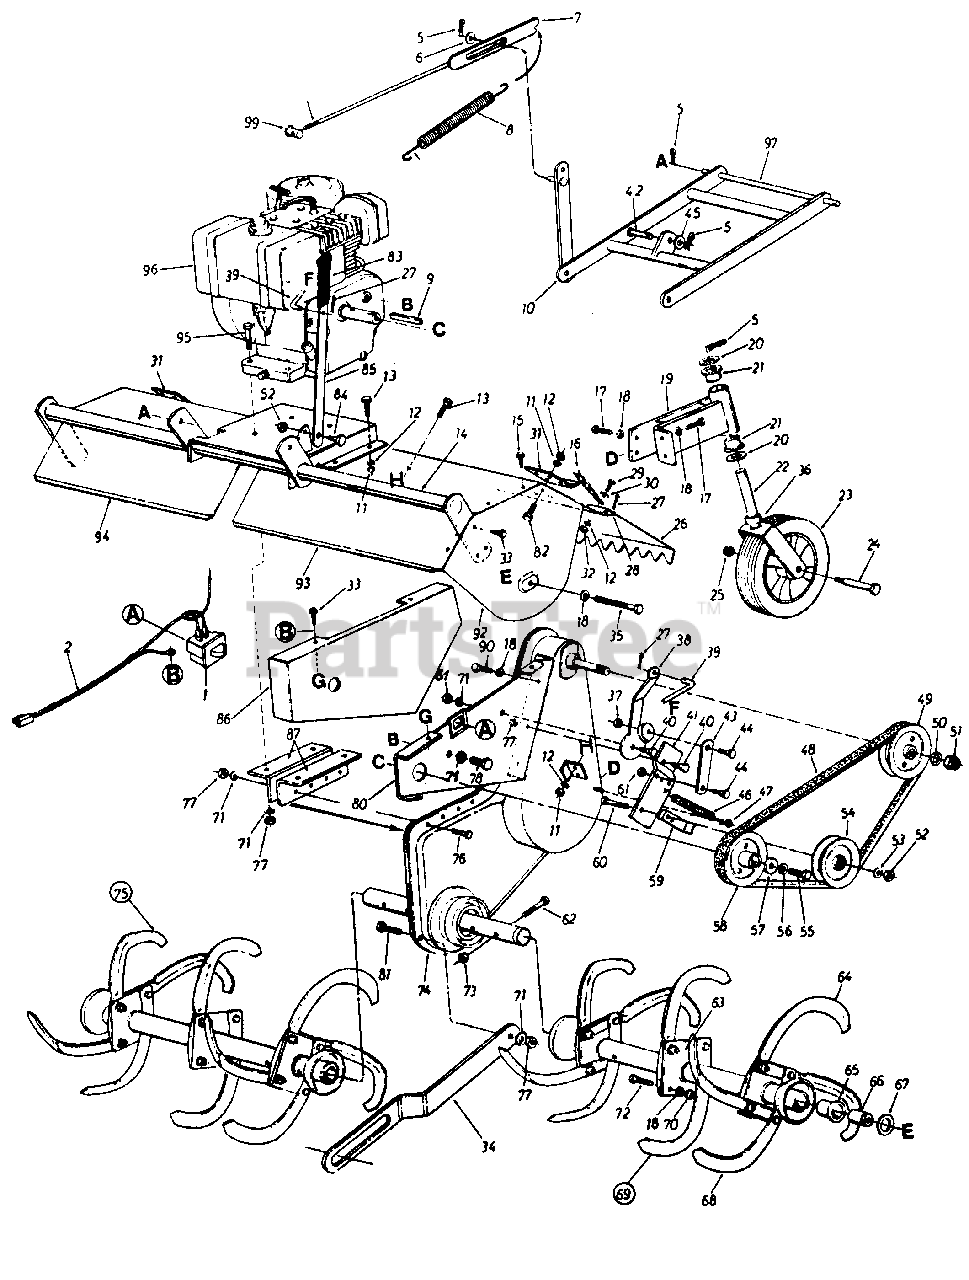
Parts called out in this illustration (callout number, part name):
1	Safety Switch
2	Wire Harness
5	Internal Cotter Pin
6	Fl-Wash. 1/2" I.D. x .93" O.D.
9	Sq. Key 1/4/' x 1/4" x 2.00" Lg.
12	L-Wash. 1/4" I.D.'
13	Hex Bolt 1/4-28 x .62" Lg.
16	#2 Dog Chain x 20" Lg.
17	Hex Wash. Hd. Self-Tap Scr. 3/8-24 x .75" Lg.
18	L-Wash. 3/8" I.D.
21	Flange Bearing 3/4 I.D. x 1.00" O.D.
24	Shoulder Bolt .623" I.D. x 3 . 62 " Lg.
25	Hex Cent. L-Nut 7/16-14 Thd.
28	L.H. Flap Rod
29	Hex Bolt 1/4-20 x .62" Lg.
30	Fl-Wash. 1/4" I.D.
33	Hex Wash. Hd. Self-Tap Scr. 1/4" x .62" Lg.
36	Spacer.752" I.D. x 1.25" O.D.
37	Hex Cent. L-Nut 5/16-18 Thd.
40	Shoulder Bolt 7/16" Dia. x 1.75" Lg.
45	Fl-Wash. .50" I.D. x 1.0" O.D. x .06
46	Extension Spring .62" O.D. x 6.12" Lg.
47	Hex Crown Nut 3/8-24 Thd.
48	"V"-Belt (Kevlar)
49	1/2" "V"-Pulley 4.75" O.D. x .625" Bore
50	L-Wash. 5/8" I.D.
51	Hex Ins. L-Nut 5/8-18 Thd.
52	Hex Cent. L-Nut 3/8-16 Thd.
53	Fl-Wash. 3/8" I.D.
54	Idler Pulley 4.0" O.D.
55	Hex Bolt
56	L-Wash. 7/16" I.D.
57	Fl-Wash. 7/16" I.D. x 1.38"
58	1/2" "V"-Pulley .475" O.D. x 1.00 Bore
61	Hex Cent. L-Nut 5/16-18 Thd.
62	Hex Bolt 7/16-14 x 2.00" Lg.
66	Spacer
67	Thrust Wash. 1/2" I.D. x 1.55n
71	L-Wash. 5/16" I.D.
72	Hex Bolt 3/8 24 x 1.5" Lg.
73	Hex Cent. L-Nut 7/16-14 Thd.
77	Hex Nut 5/16-18 Thd.
78	Hex Bolt 5/16-24 x .62"
80	Clutch Support Bracket
81	Shld. Bolt .435 Dia. x .265 5/16-18 Thd.
82	Hex Bolt 1/4-28 x .75" Lg.
83	Plastic Grip
84	Shoulder Bolt .498 Dia. x .212 Lg.
96	8 H.P. Engine
97	Hitch Rod
99	Ferrule
